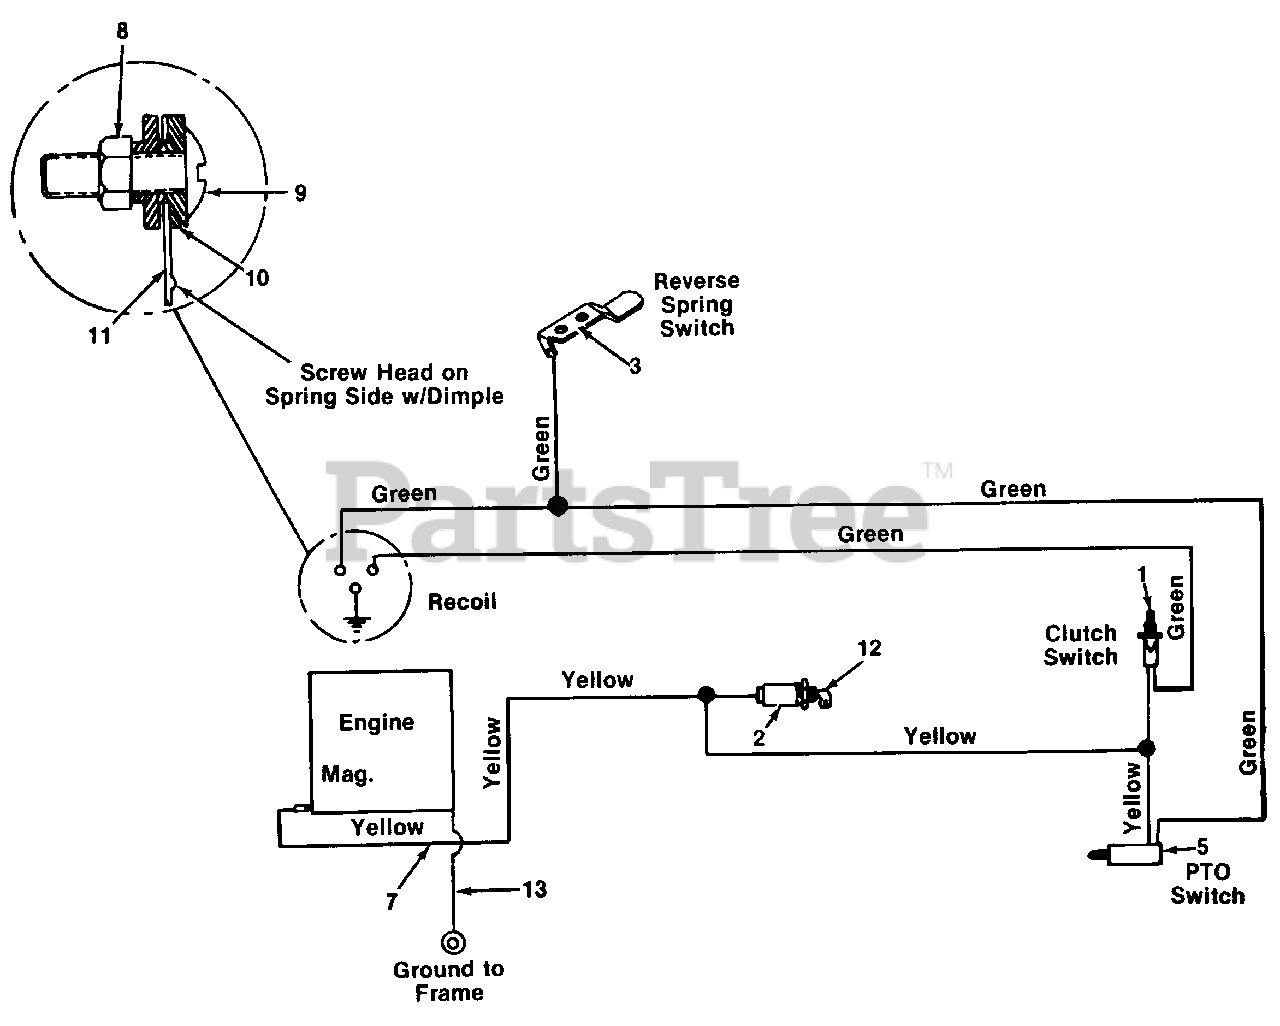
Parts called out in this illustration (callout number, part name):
1	Safety Switch
2	Key Switch
3	Spring Switch
5	Safety Switch
7	Convoluted Conduit 24" Lg.
8	Hex Nut #10-24
9	Truss Mach. Scr. #10-24 x .62
10	Fiber Washer
11	Spring Switch
12	Ignition Key
13	Ground Wire
